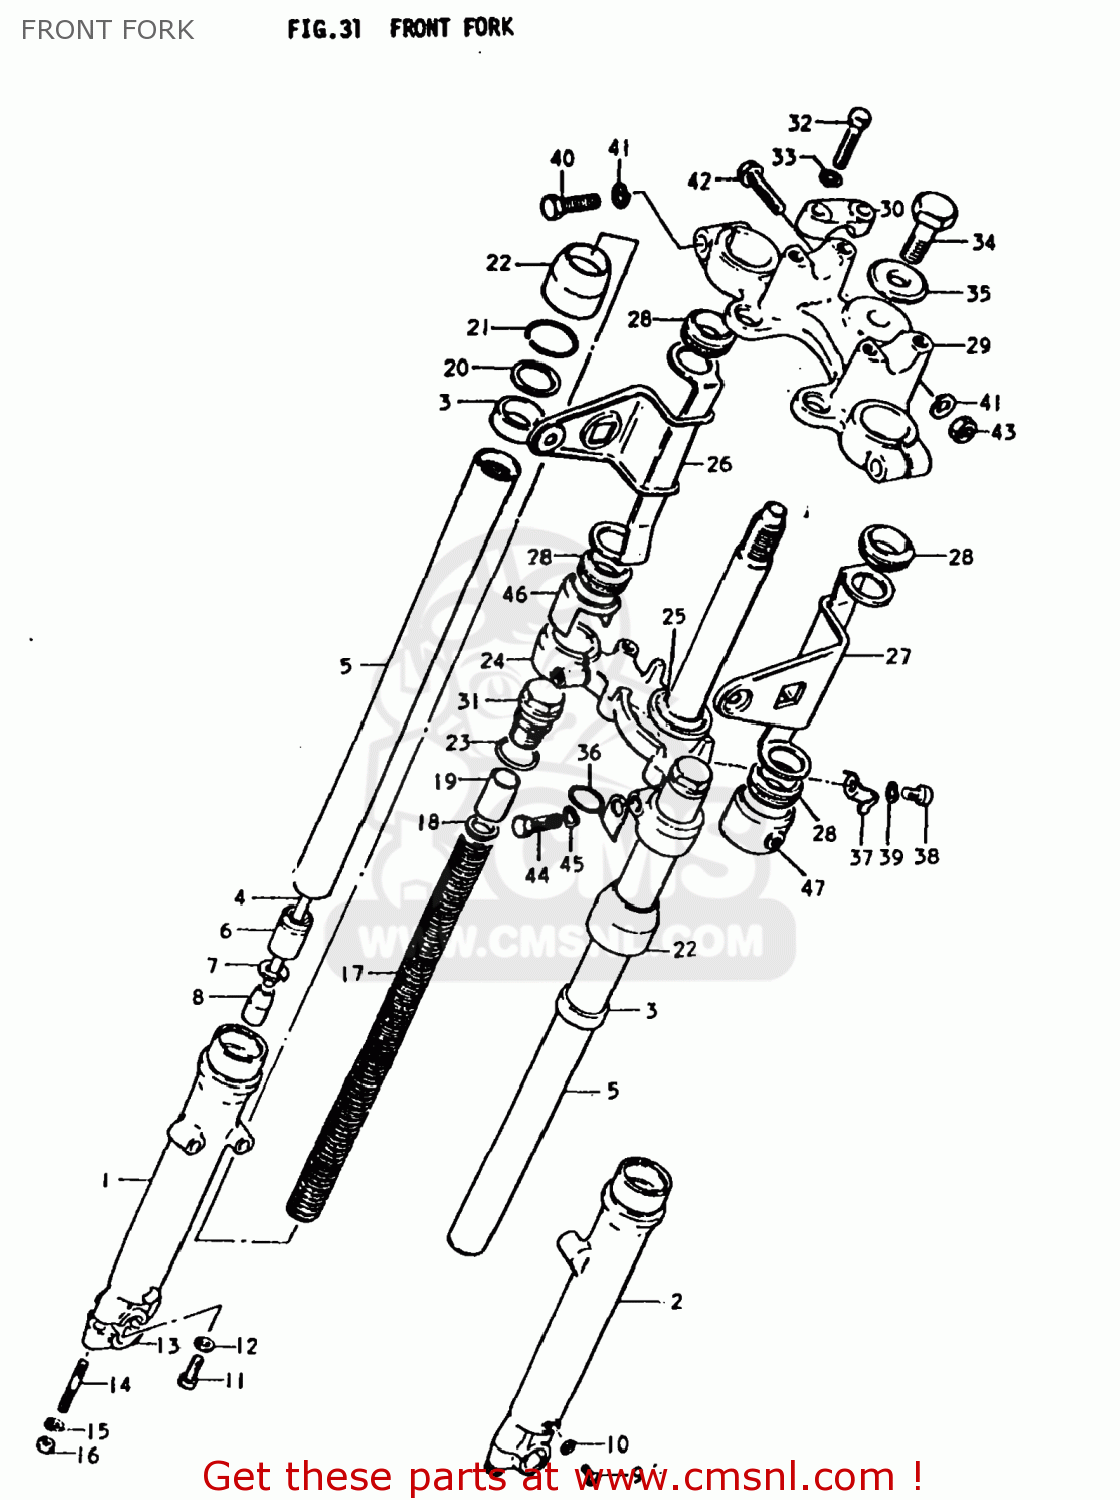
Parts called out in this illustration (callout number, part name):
1	TUBE,OUTER,RIGHT
2	TUBE,OUTER,LEFT
3	SEAL,OIL
4	RING,FORK BACK UP
5	CIRCLIP,FORK OIL SEAL
6	BOLT,FORK CYLINDER(10X25)
7	GASKET (NAS)
8	PIECE,OIL LOCK
9	CYLINDER,FRONT FORK
10	TUBE,FORK,INNER
11	BOOT
12	BAND,BOOT
13	SCREW
14	SPRING,FRONT FORK
15	GUIDE,FRONT FORK SPRING C
16	SPACER,FRONT FORK SPRING
17	CAP,FORK INNER TUBE
18	O RING
19	CAP,FR FORK
20	GASKET
21	BRACKET,HEADLAMP HOUSING
22	BRACKET,HEADLAMP,LEFT
23	STEM,STEERING
24	RACE,STEERING OUTER LWR
25	HEAD,STEERING STEM
26	HOLDER,HANDLEBAR
27	LOCK WASHER
28	BOLT
29	WASHER
30	BOLT,STEERING STEM HEAD
31	BOLT
32	WASHER,LOCK 12
33	BOLT 8X55
34	WASHER
35	NUT
36	CLIP
37	BOLT 12X45
38	WASHER
39	GUIDE,CABLE
40	BOLT
41	CLIP,BRAKE CABLE
42	SCREW
43	LOCK WASHER
44	SCREW
45	GASKET,DRAIN,PLUG (NAS)
